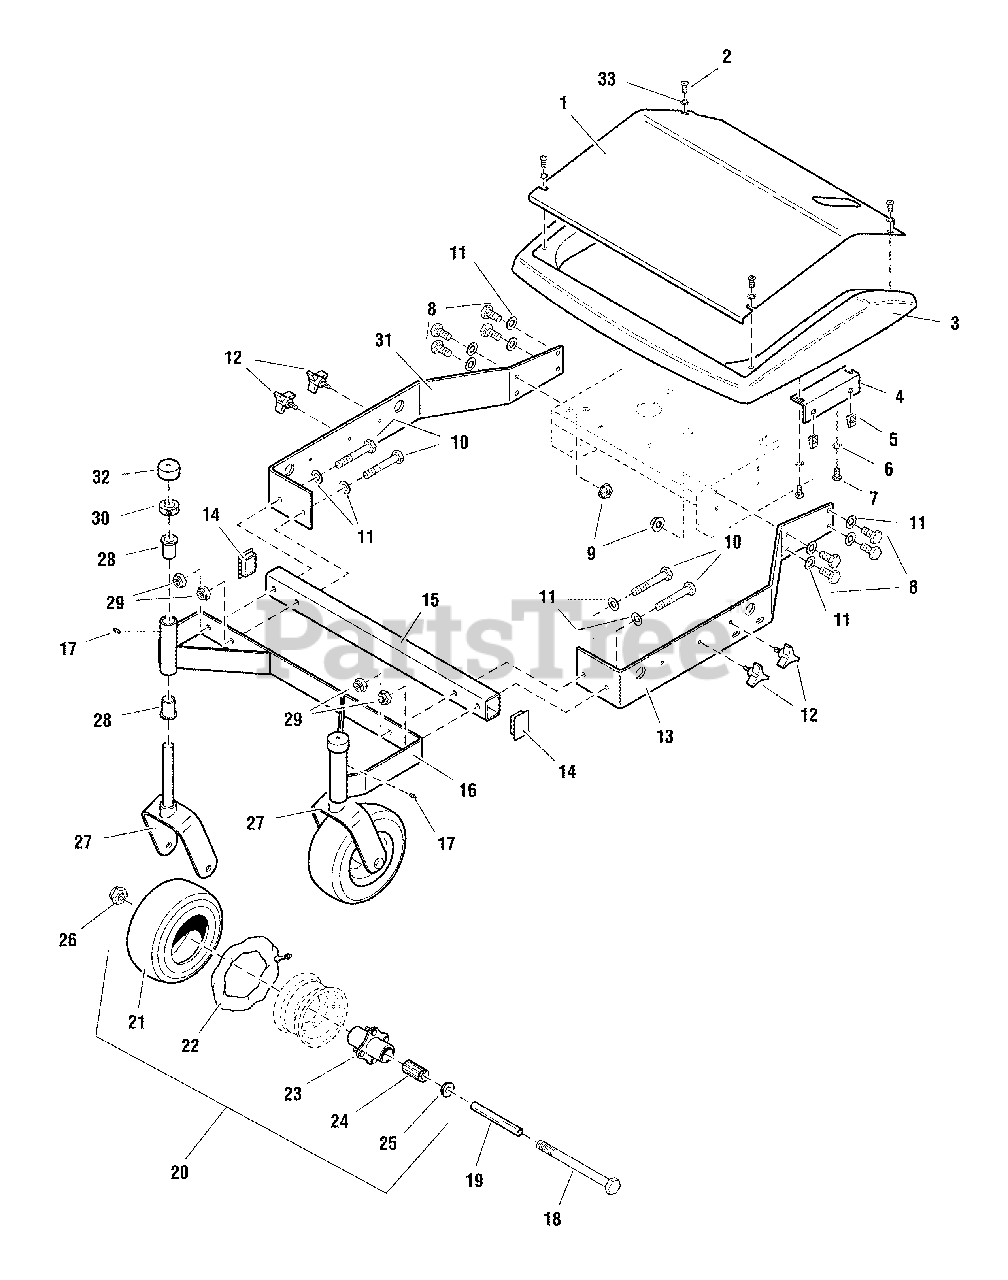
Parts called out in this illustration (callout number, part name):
1	GUARD, INSERT (BRIGGS)
2	SCREW, 1/4-20 X 1/2 ALLEN BH
3	GUARD, MOWER DECK
4	BRACKET, GUARD
5	CLIP, BODY , 5/16-18 FOR 7 GA.
6	WASHER, 1/4 LOCK
7	BOLT, 1/4-20 X 3/4 GD5 YZ
8	BOLT, 3/8-16 X 1 GD5 YZ
9	NUT, 3/8-16 HEX SERRATED FLANGE
10	BOLT, 3/8-16 X 2-1/2 GD5 YZ
11	WASHER, 3/8 SAE
12	KNOB, PLASTIC, 5/16-18 X 3/4
13	RAIL, DECK FRAME - LEFT
14	CAP, 1-1/2 X 2 X 11GA, PLASTIC
15	TUBE, CROSS
16	WELD, CASTER MOUNT
17	GREASE FITTING, 1/4-28 STRAIGHT
18	BOLT, 1/2-13 X 5-1/2 GD5 YZ
19	AXLE, CASTER WHEEL
20	TIRE ASSM, 9 X 3.5 X 4, SILVER
21	TIRE, FRONT, 9 X 3.5 X 4, TIRE ONLY
22	9X350-4 TUBE ONLY
23	HUB, 4 Bolt, Silver
24	BEARING, ROLLER
25	RETAINER, BEARING
26	NUT, 1/2-13 HEX NYLON LOCK
27	WELD, CASTER YOKE
28	BUSHING, FLANGE, 3/4 X 1+69878956
29	NUT, 3/8-16 HEX NYLOCK FLANGE
30	COLLAR, 3/4 SPLIT
31	RAIL, DECK FRAME - RIGHT
32	CAP,VINYL, 1.375 X 1
33	WASHER, 1/4 SAE (5025154)
